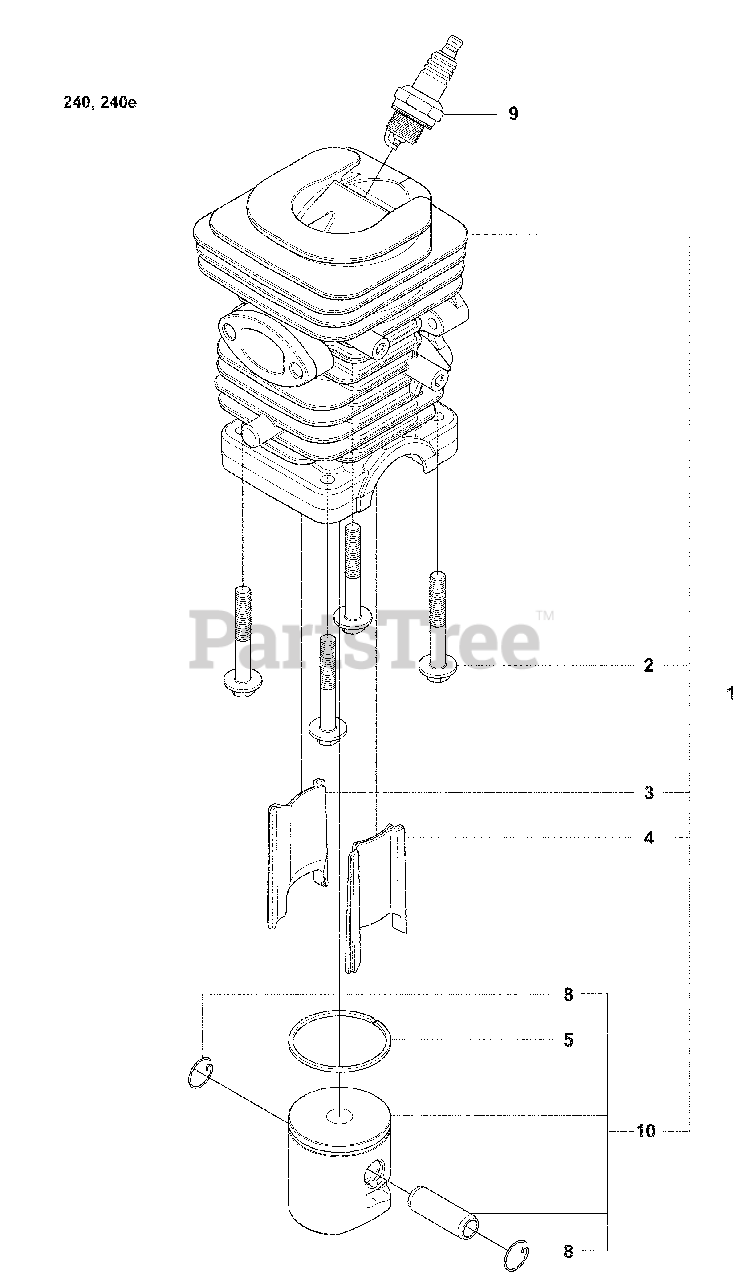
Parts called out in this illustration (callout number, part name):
2	BOLT, CYLINDER
3	INSERT, TRANSFER LEFT
4	INSERT, TRANSFER RIGHT
5	PISTON RING
8	PISTON PIN RETAINER
9	PLUG-SPARK (RCJ-7Y)
10	KIT 38cc PISTON
11	KIT, CYLINDER & PISTON
